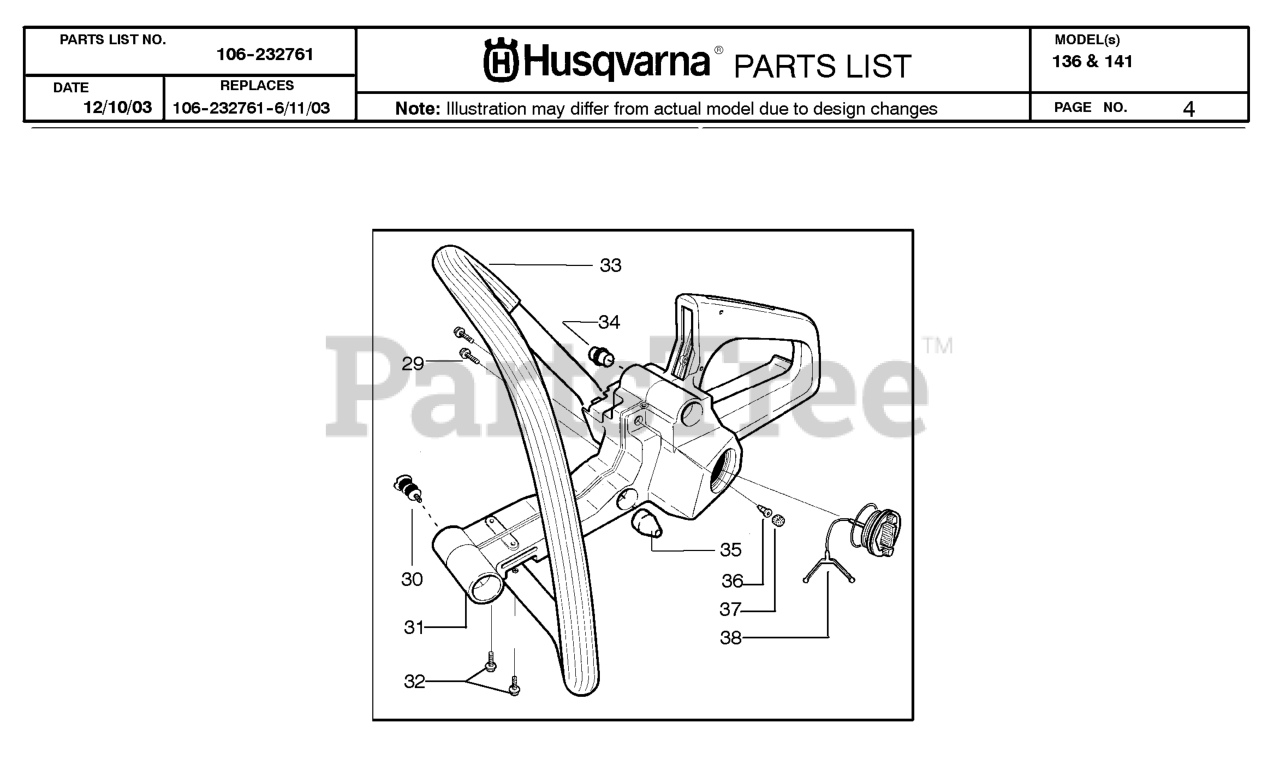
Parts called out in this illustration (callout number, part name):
33	FRONT HANDLE
34	FRONT HANDLE ISOLATOR
35	SHOCK MOUNT(X2) 36/41
36	VALVE-CHECK (DUCKBILL)
37	BRONZE PLUG
38	FUEL CAP KIT
